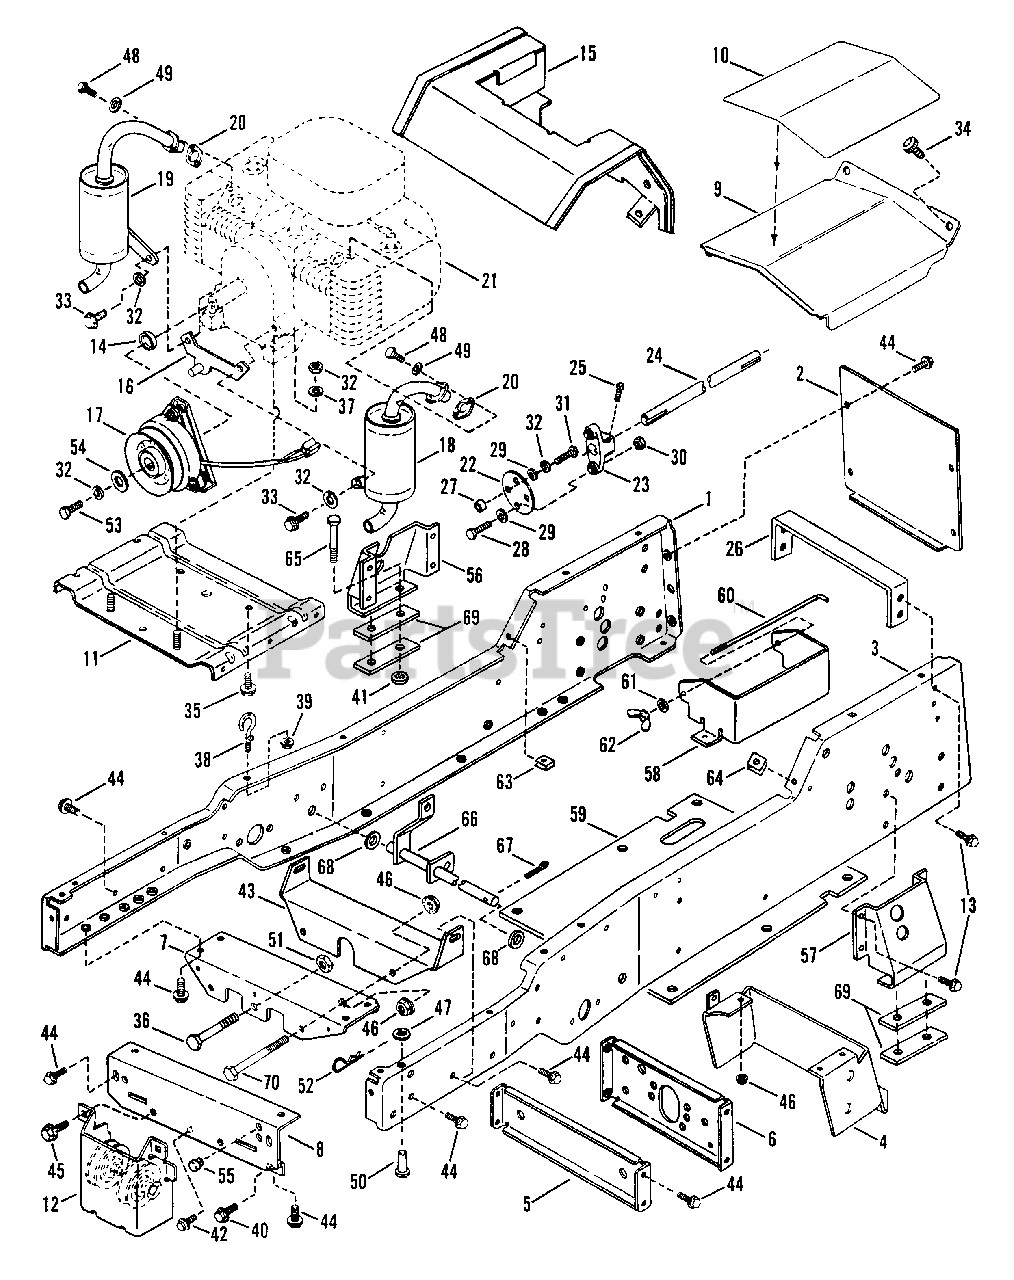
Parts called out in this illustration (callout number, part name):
1	CHANNEL, Right Hand Frame
2	PLATE, Rear Cover
3	CHANNEL, Left Hand Frame
4	DRAW-BAR
5	BRACE, Forward
6	BRACE, Rear Cross
7	CHANNEL, Front Axle Support
8	PLATE, Front Frame
9	COVER, Console
10	DECAL, Console Cover
11	BASE, Engine
12	ASSEMBLY, Mule Drive
13	SCREW, 3/8-16 x 1/2" S.T.
14	SPACER, Clutch
15	ASSEMBLY, Heat Shield
16	BRACKET, Clutch Retainer
17	KIT, Electric Clutch
18	MUFFLER, Left Hand
19	MUFFLER, Right Hand
20	GASKET, Exhaust
22	DISC, Flex Coupling
23	HUB, Flex Coupling
24	SHAFT, Drive
25	SETSCREW, 5/16-18 x 1/2" Square Head
26	STRAP, Cross
27	SPACER, Flexible Coupling
28	SCREW, 3/8-16 x 1" Hex Head Cap, Grade 2
29	WASHER, 3/8" Flat
30	LOCKNUT, 3/8-16 Hex
31	SCREW, 3/8-16 x 1-1/2 Hex Head Cap Grade 5
32	WASHER, 3/8 Split Lock
33	SCREW, 3/8-16 x 7/8" Hex Head Cap Grade 5
35	SCREW, 7/16-14 x 3/4" HHST
36	SCREW, 1/2-20 x 4" HHC Grade 5
37	NUT, 3/8-16 Hex
38	HOOK, Hood Latch
39	NUT, 5/16-18 Hex Flange Lock, Grade 5
40	SCREW, 1/4-20 x 5/8" Hex Head Flange, Self-Tapping
41	RETAINER, 3/8 Bolt
42	SCREW, 1/4-20 x 3/8" Hex Head Flange, Self-Tapping
43	BRACE, Axle
44	SCREW, 5/16-18 x 5/8" Hex Head Flange, Self-Tapping
45	BOLT, 3/8-16 x 3/4" Hex Flange Lock
46	NUT, 3/8-16 Hex Flange Lock
47	NUT, 1/4 Push
48	SCREW, 5/16-18 x 7/8" Socket Head Cap
49	WASHER, 5/16 Split Lock
50	PIN, 1/4 x 7/8" Clevis
51	NUT, 1/2-20 Hex Lock
52	PIN, Hair
53	SCREW, 3/8-24 x 1-1/2" Hex Head Cap, Grade 2
54	WASHER, .406 I.D. x 1.38 Flat
55	RELIEF, Strain
56	SUPPORT, R.H. Axle
57	SUPPORT, L.H. Axle
58	BRACKET, Battery
59	STIFFENER, Frame
60	CLAMP, Battery
61	WASHER, 1/4 SAE
62	WING-NUT, 1/4-20 Thread
63	U-NUT, 1/4-20
64	CLIP
65	SCREW, 3/8-24 x 3-3/4" Hex Head Cap, Grade 5
66	SHAFT & LEVER
67	COTTER-PIN, 3/32 x 3/4"
68	WASHER, 3/8 SAE
69	SPACER, Transmission
70	SCREW, 3/8-16 x 4" Hex Head Cap, Grade 5
